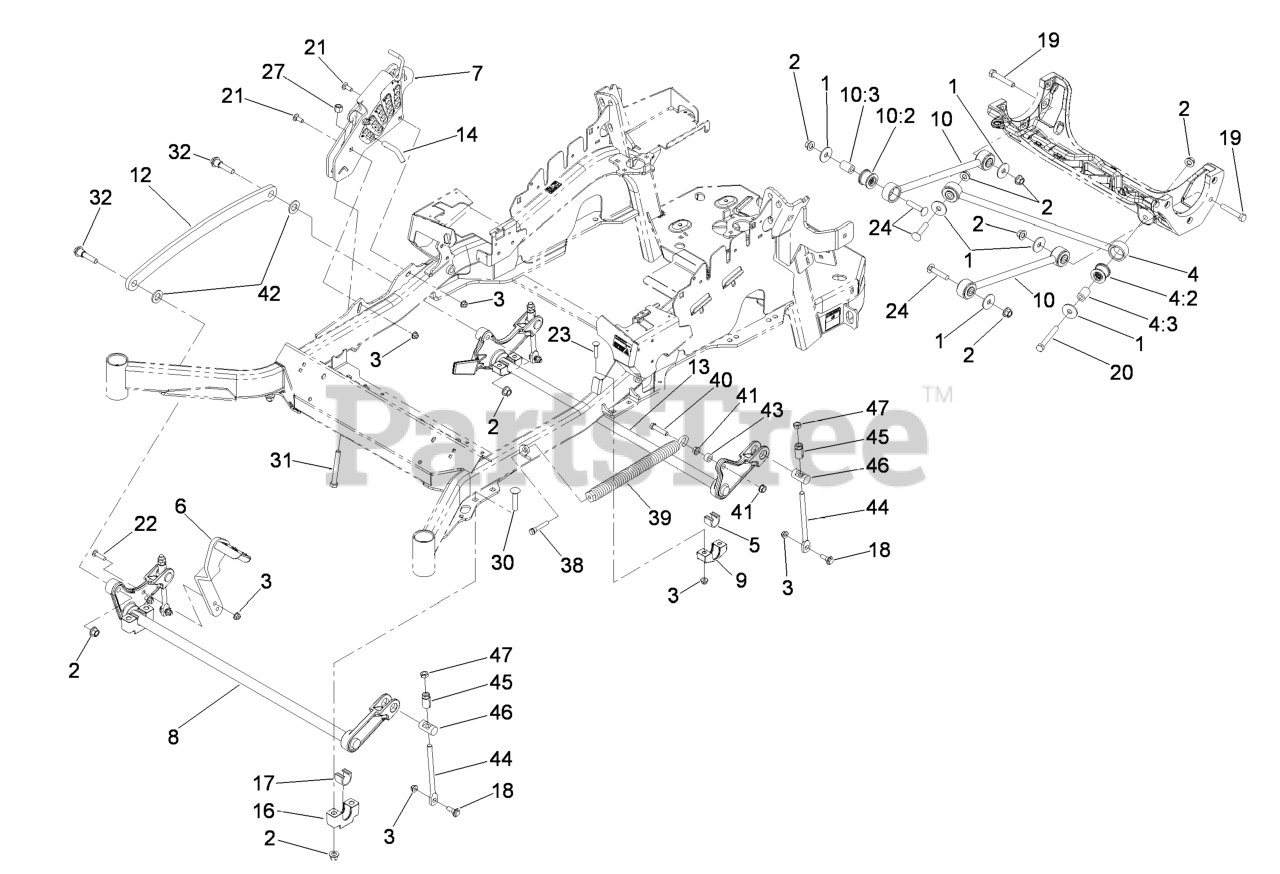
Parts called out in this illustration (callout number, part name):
1	WASHER-THRUST
2	Nut-Lock 1/2-13
3	NUT-HF, NI
4	PANHARD ROD ASM
4:2	BUSHING-SUSPENSION, RUBBER
5	BEARING-CROSS SHAFT, REAR
6	LEVER-FOOT
7	HOC ASM
10	DECK STRUT ASM
10:2	BUSHING-SUSPENSION, RUBBER
12	LINK-LIFT, DECK
13	LIFT-DECK, REAR
14	PIN-HOC
16	SUPPORT-CROSS SHAFT, BEARING
17	BEARING-CROSS SHAFT, FRON
18	SCREW-SHOULDER, HHF
19	SCREW-HH
20	SCREW-HH
21	BOLT-CARR
22	SCREW-CARR
23	SCREW-CARR
24	SCREW-CARR
27	NUT-LOCK, NI
30	Bolt-Carriage 1/2-13 X 2 1/2 Spl Neck
31	BOLT-TAP
32	SCREW-HHF, SHOULDER
38	BOLT-SHOULDER
39	SPRING-EXTENSION
40	SCREW-HH
42	WASHER-FLAT
44	LINK-ADJUSTER, DECK LIFT
45	ADJUSTER-LIFT, DECK
46	TRUNNION
47	NUT-JAM
